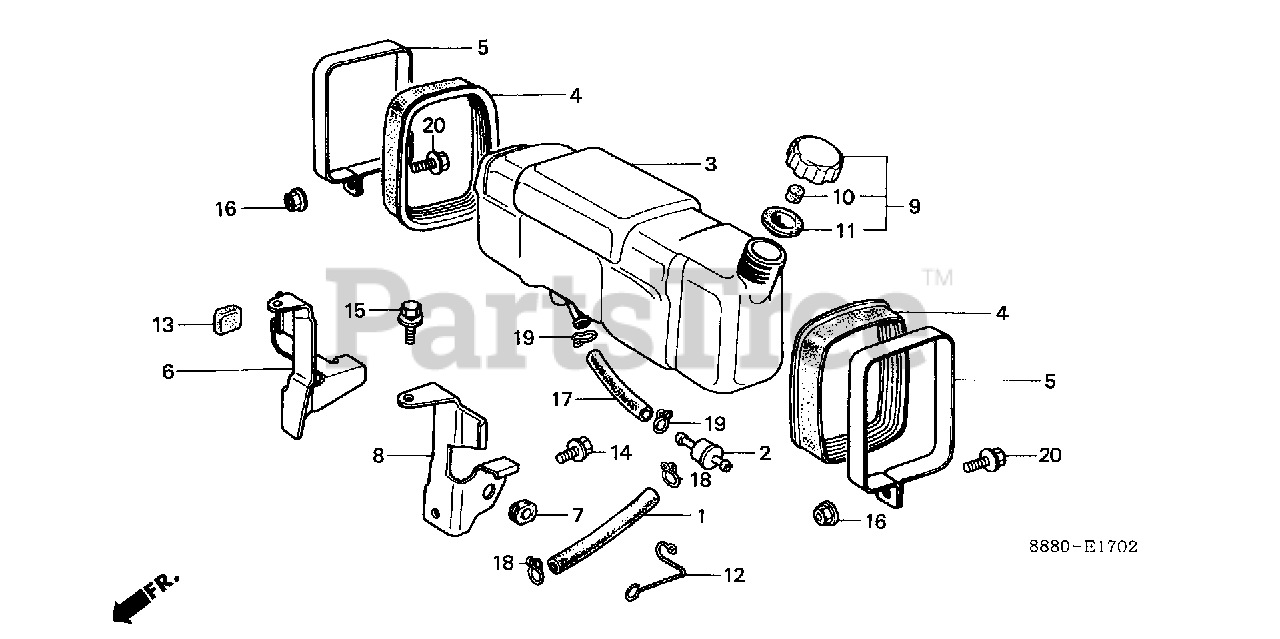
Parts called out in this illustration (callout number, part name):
1	TUBE, FUEL (4.5X120) (NOT AVAILABLE)
1	BULK HOSE, FUEL (4.5X3000) (4.5X120)
2	FILTER, FUEL
3	TANK, FUEL
4	RUBBER, TANK SEAT
5	BAND, FUEL TANK
6	STAY A, TANK
7	GROMMET, FUEL TUBE
8	STAY B, TANK
9	CAP ASSY., FUEL TANK
10	SPONGE, FUEL CAP BREATHER
11	GASKET, FUEL CAP
12	CLAMP, IGNITION WIRE
13	RUBBER, CUSHION (NOT AVAILABLE)
14	BOLT, FLANGE (6X12) (CT200)
15	BOLT-WASHER (6X10)
16	NUT, FLANGE (6MM)
17	BULK HOSE, FUEL (5.5X3000) (5.3X95)
17	BULK HOSE, FUEL (5.5X3000) (5.3X110)
18	CLIP, TUBE (B8)
19	CLIP, TUBE (B10)
20	BOLT, FLANGE (6X12)
